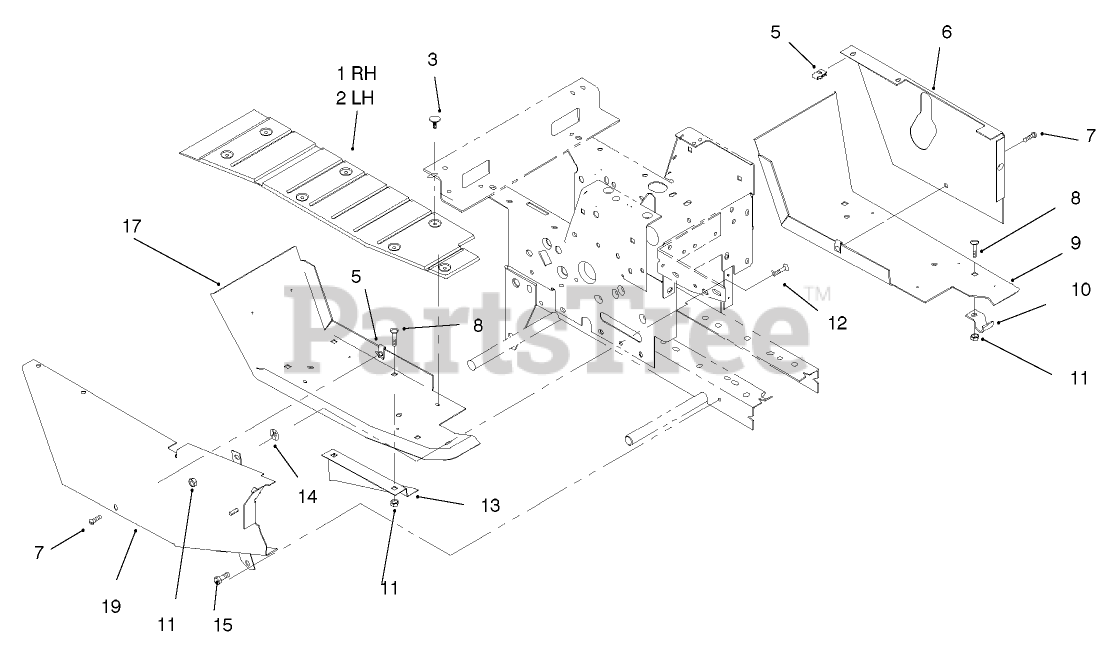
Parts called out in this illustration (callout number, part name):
1	PAD-FOOT RH
2	PAD-FOOT LH
3	FASTENER-PANEL
6	COVER-LH
7	SCREW-PPH
8	BOLT-CARR
9	PINION SHAFT
9	FOOTREST-LH
10	BRACKET
11	NUT-LOCK, NI
12	BOLT-CARR
13	GUIDE-LOWER BELT
17	FOOTREST-RH
18	NOT A SERVICE PART-SEE SERVICE REP. DISC
